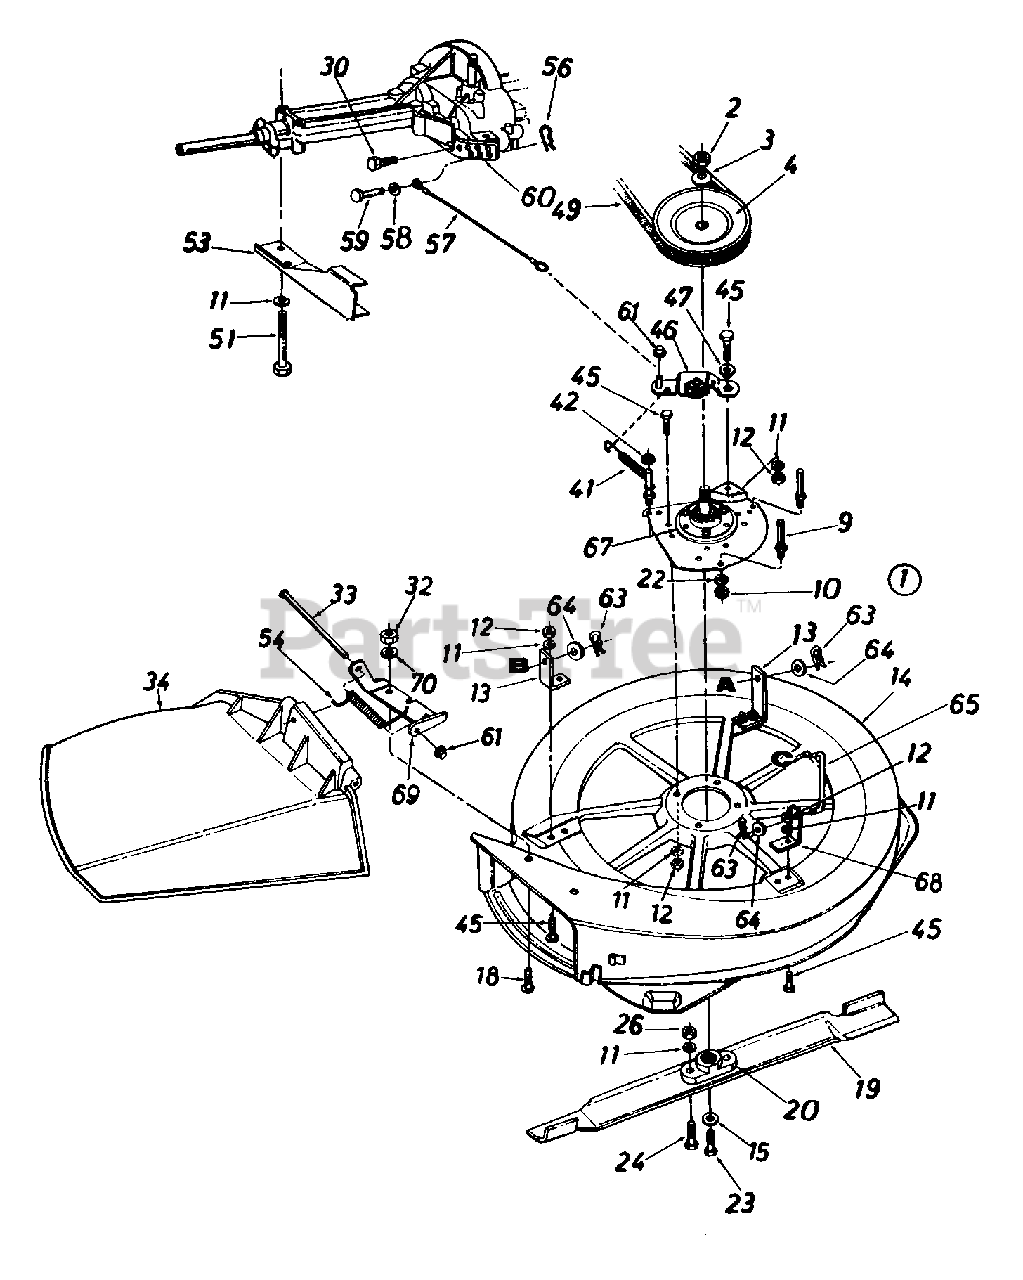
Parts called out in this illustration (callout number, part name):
1	30" S.D. Deck Ass'y. Comp.
2	Hex Jam Nut 5/8 - 18 Thd.
3	Bell-Wash. .630" I.D. x 1.25"
4	5/8 V-Pulley .75" I.D. x 7"
9	Stud 3/8 - 16 x 2.75" Lg.
10	Hex Jam Nut 3/8 - 16 Thd.
11	L-Wash. 5/16" I.D.
12	Hex Nut 5/16 - 18 Thd.
18	Truss Scr. 1/4 - 20 x .75" Lg.
19	30" High Lift Blade
20	Blade Adapter
22	L-Wash. 3/8" I.D.
23	Hex Bolt 3/8 - 24 x 1.0
24	Hex Bolt 5/16 - 24 x 1.0" Lg.
26	Hex Nut 5/16 - 24 Thd.
30	Hex Bolt 1/4 - 20 x .50" Lg.
32	Hex Nut 1/4 - 20 Thd.
33	Hinge Pin
34	Chute Ass'y. Comp.
41	Extension Spring .5" O.D. x 3.2" Lg.
42	Push Speed Nut
45	Hex Bolt 5/16 - 18 x .75"
46	Blade Brake Brkt. Ass'y.
47	Shoulder Spacer .500" Dia.
49	"V"-Belt
51	Hex Bolt 5/16 - 18 x 2.75"
56	Int. Cot. Pin 5/16" Dia.
57	Brake Cable 9.75" Lg.
58	FL-Wash. .281" I.D. x .50"
59	Clevis Pin 1/4" Dia.
63	Int. Cotter Pin 1/2" Dia.
64	FL-Wash. .531" I.D. x .930"
65	Deck Link 3.9" Lg.
67	Blade Spindle Ass'y. Comp.
68	Weld Bracket
69	Hinge Mtg. Brkt.
70	Bell-Wash. 1/4" I.D.
